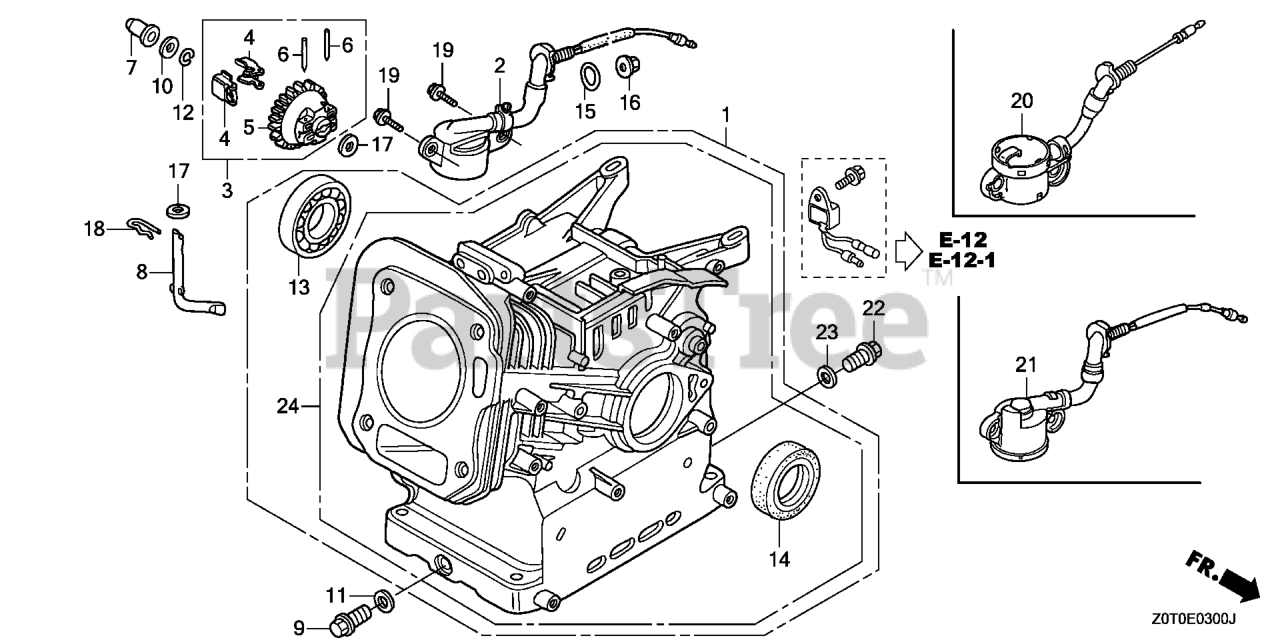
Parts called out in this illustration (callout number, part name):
1	CYLINDER ASSY.
3	GOVERNOR ASSY.
4	WEIGHT, GOVERNOR
5	HOLDER, GOVERNOR WEIGHT
6	PIN, GOVERNOR WEIGHT
7	SLIDER, GOVERNOR
8	SHAFT, GOVERNOR ARM
9	BOLT, DRAIN PLUG
11	WASHER, DRAIN PLUG (10.2MM)
12	CLIP, GOVERNOR HOLDER
13	BEARING, RADIAL BALL (6205)
13	BEARING, RADIAL BALL (6205) (NSK)
14	OIL SEAL (25X41X6)
15	O-RING (14MM) (ARAI) Use up to Engine SN 2949254.
16	NUT, FLANGE (10MM)
17	WASHER, PLAIN (6MM)
18	PIN, LOCK (8MM)
19	BOLT, FLANGE (6X12) Use up to Engine SN 1543277.
20	SWITCH ASSY., OIL LEVEL
